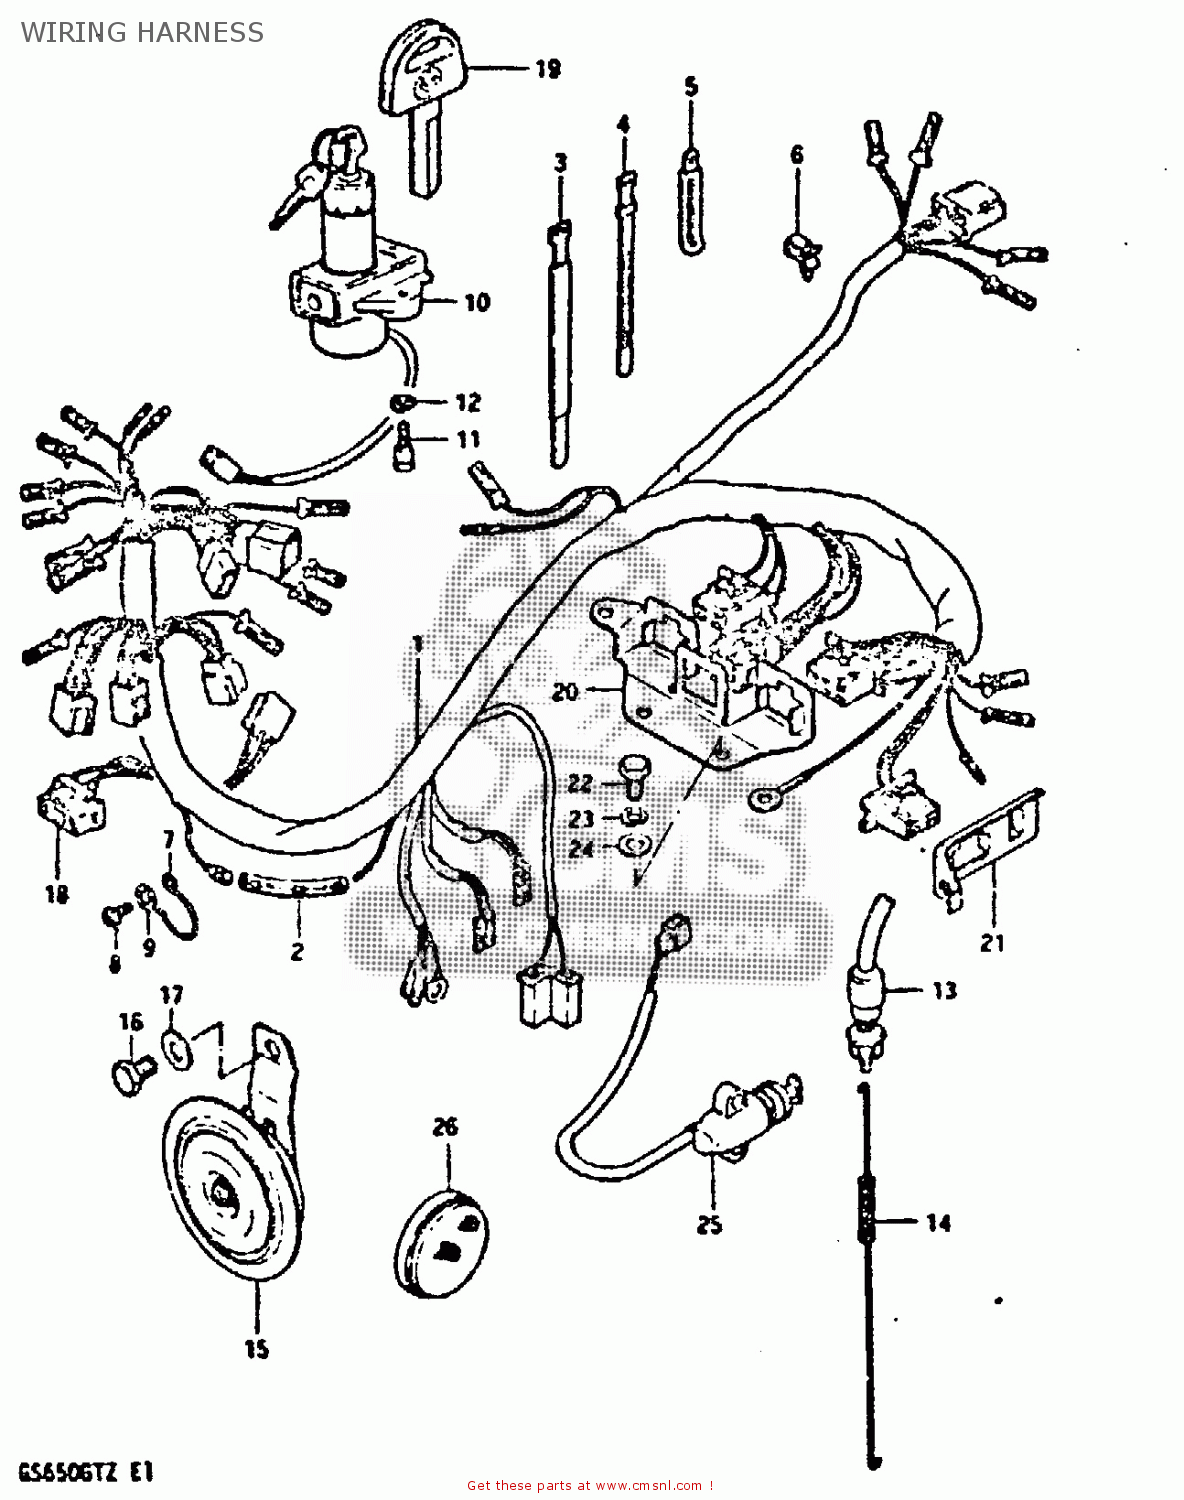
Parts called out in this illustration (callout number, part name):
1	WIRING HARNESS
2	DIODE
3	CLAMP
4	CLAMP
5	CLAMP
6	CLIP
7	GUIDE,WIRING HARNESS
8	SCREW
9	WASHER
10	LOCK ASSEMBLY,STEERING
11	BOLT
12	LOCK WASHER
13	SWITCH ASSEMBLY,STOP LAMP
14	SPRING
15	HORN ASSEMBLY
16	BOLT 8X12
17	WASHER
18	LEAD WIRE,HEADLAMP
19	KEY,BLANK
20	PLATE, COUPLER HOLDER (A)
21	PLATE, COUPLER HOLDER (B)
22	BOLT
23	LOCK WASHER
24	WASHER
25	SWITCH ASSEMBLY,SIDE STAND
